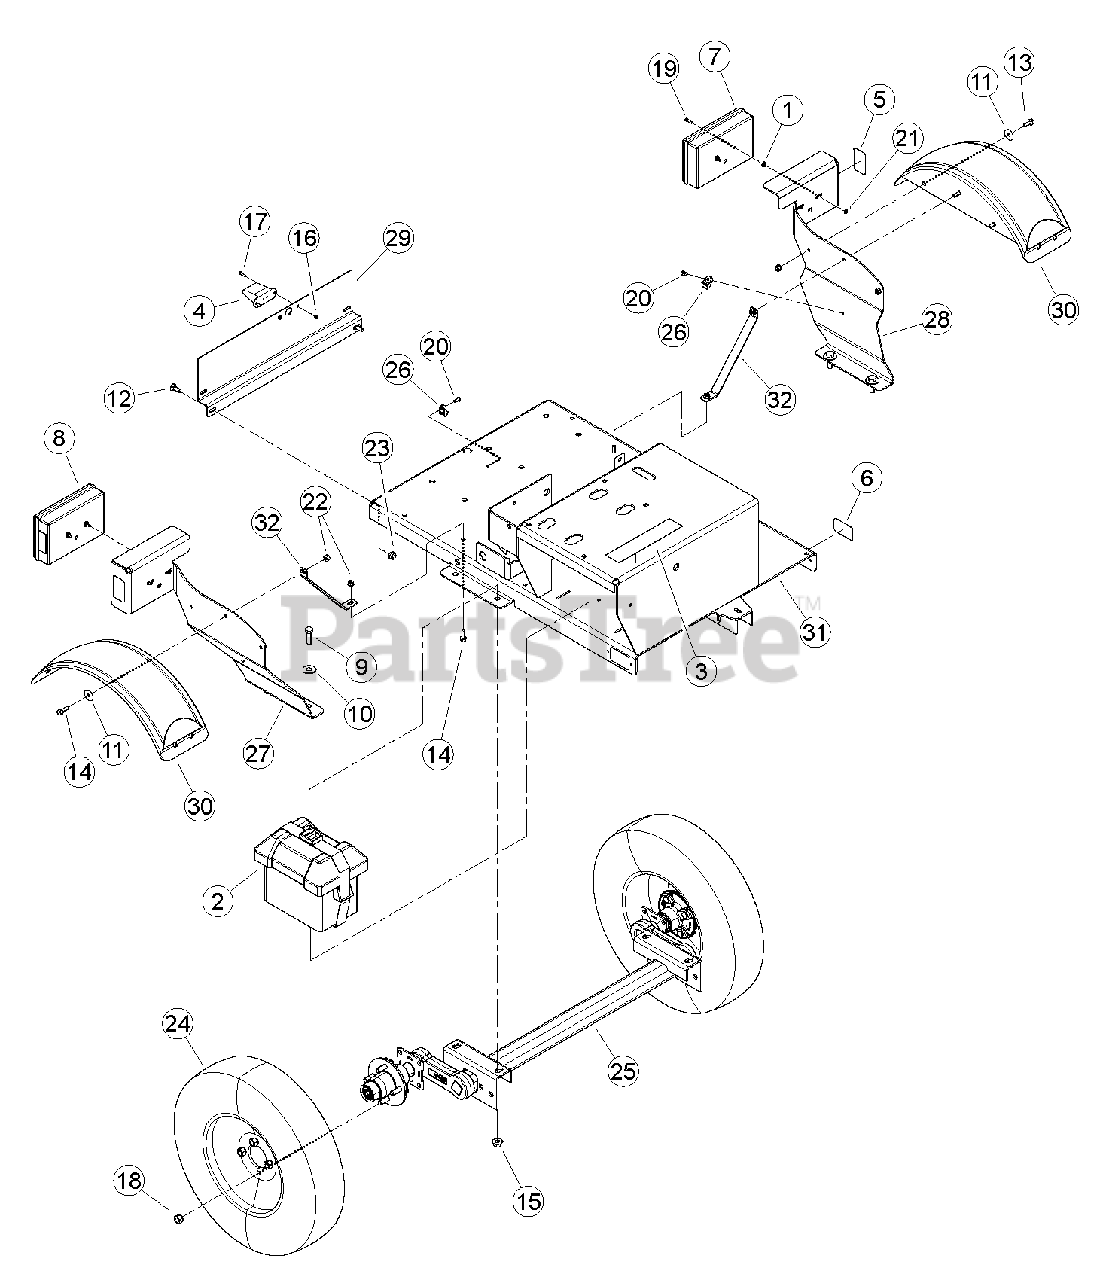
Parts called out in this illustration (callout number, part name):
1	GROMMET, 1/4 X 5/8 RUBBER
2	BOX, SMALL BATTERY
3	DECAL, CHIPPER ENGAGEMENT
4	LIGHT, LICENSE PLATE
5	REFLECTOR, WIDE ANGLE RED
6	REFLECTOR, WIDE ANGLE AMBER
7	LIGHT, TAIL RH
8	LIGHT, TAIL LH
9	BOLT, 1/2-13 X 1-1/2 HEX HD GR5
10	WASHER, 1/2 FLAT
11	WASHER, 5/16" FENDER ZP
12	BOLT, 3/8-16 X 1 GR5 CRG
13	BOLT, 5/16 X 7/8 FLANGE NC
14	BOLT, 5/16 X 1 FLANGE NC
15	NUT, 1/2-13 NYLOCK FLANGE
16	NUT, 10/24 NYLOCK TYPE NM ZP
17	SCREW, #10-24 X 3/4" PAN HD PH ZP MCH
18	NUT, 1/2-20 WHEEL
19	BOLT, 10-24 X 3/4" HHCS GR8 PLAIN
20	RIVET, AL BLIND 1/4 X 3/4 DOME HEAD
21	NUT, #10-24 K-LOCK ZP
22	NUT, 5/16-18 NYLOCK FLANGE
23	NUT, 3/8-16 NYLOCK FLANGE
24	ASSEMBLY, 5.30-12 TIRE + SPOKE RIM
25	AXLE, 1000LB TORSION
26	CLAMP, CABLE MOUNT
27	BRACKET, RH FENDER "CE"
28	BRACKET, LH FENDER "CE"
29	PLATE, MOUNTING
30	FENDER, BLACK PLASTIC DRILLED
31	WELDMENT, C/S TRAILER
32	BRACE, FENDER
